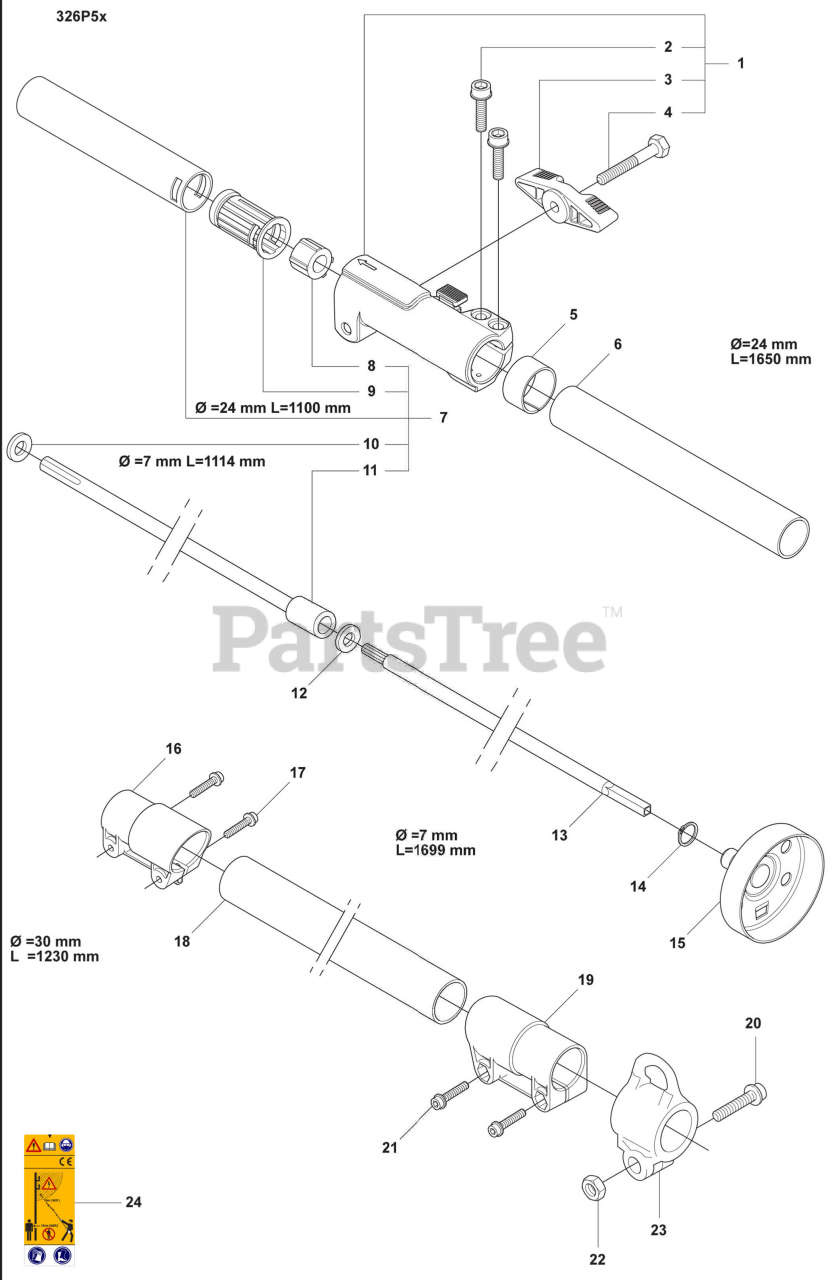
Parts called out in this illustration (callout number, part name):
1	Clamping Sleeve
2	Screw, M5 X 25 Pl Hsc Ih X
6	Inner Tube Assembly
7	Tube
8	Bushing
9	Plug
11	Drive Shaft
13	Drive Shaft
15	Clutch Drum
16	Locking Sleeve
18	Pipe
19	Locking Sleeve
20	Screw, M5 X 16 Ms Hsc Ih X
22	Hex Nut, M5 X .80 DIN
23	Harness Holder
